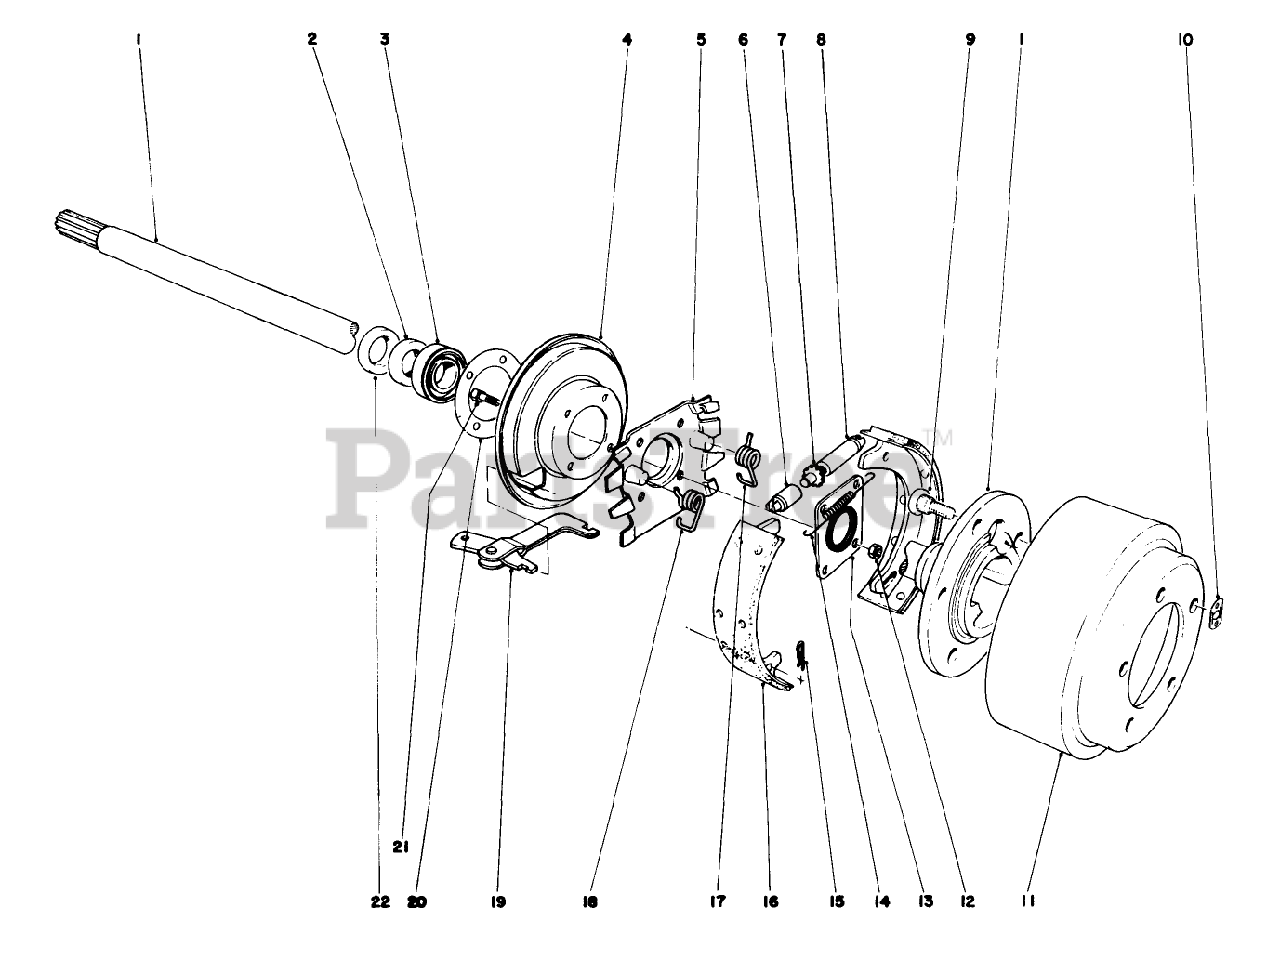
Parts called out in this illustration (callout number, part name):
1	AXLE SHAFT L.H.
2	Oil Seal
3	BEARING ASM
4	SHIELD-DUST
5	Torque Spider
6	SOCKET-SCREW, ADJUSTING
7	SCREW-ADJUSTING
8	NUT-PIVOT
9	STUD-DRIVE
10	CLIP-RETAINING
11	DRUM-BRAKE
12	NUT-HEX
13	SEAL-GREASE
14	SPRING-SCREW, ADJUSTING
15	RETAINER-LEVER, BRAKE
16	Package-Lined Shoes
17	SPRING-RETURN, LH
18	SPRING-RETURN, RH
19	BRAKE LEVER ASSY
20	Gasket Wheel Baaring
21	Screw
22	RING-RETAINING, WHEEL BEARING
